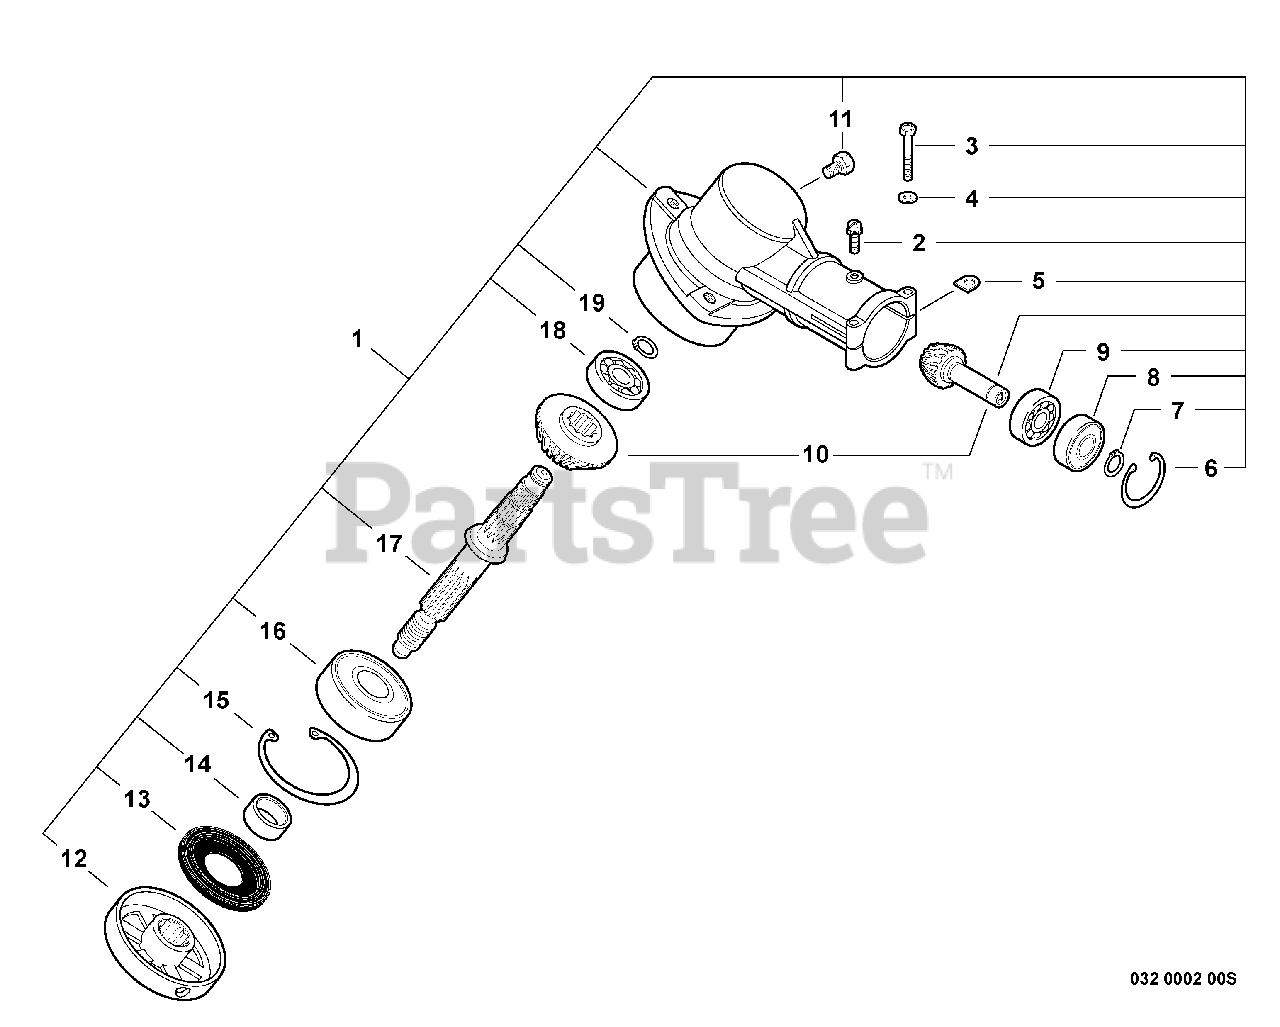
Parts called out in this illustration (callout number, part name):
1	GEAR CASE ASSY
2	SCREW 5×10
3	BOLT 5×35 SP
4	WASHER, FLAT 5.5×10×0.8
6	RING, SNAP Ø22
7	RING, SNAP Ø10
8	BEARING, BALL 6900Z
9	BEARING, BALL 6900
10	GEAR SET
11	BOLT M8×8
12	PLATE, ADAPTOR - UPPER
13	SEAL, OIL 22
14	SPACER 11.8×15×9
15	RING, SNAP Ø32
16	BEARING, BALL - 6201 C3
17	SHAFT, GEAR
18	BEARING, BALL 609
19	RING, SNAP Ø12
